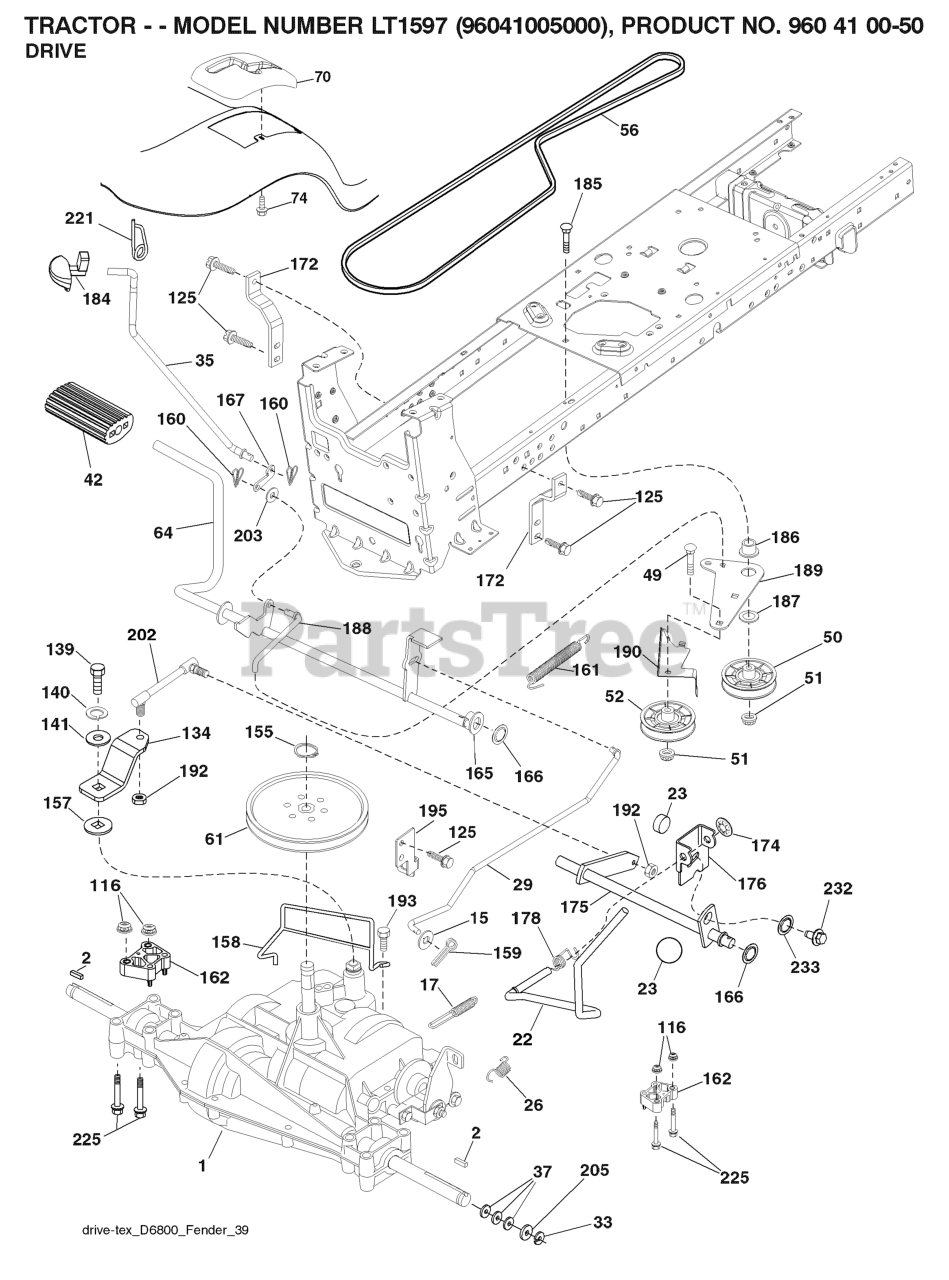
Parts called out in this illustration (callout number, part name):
2	SQUARE KEY
15	WASHER
17	SPRING.BRAKE.PEERLESS.TEX
22	ROD.SHIFT.FENDER.TLT.2006
23	KNOB.DUCKHEAD.1/2
26	SPRING.BRAKE.RTN.GR.DR
29	ROD.BRAKE.PEERLESS
35	ROD.CNTRL.PARK.PREDATOR.LT.TEX
42	PEDAL COVER T
50	IDLER.FLAT.910.OFFSET
51	NUT LOCK FLG 3/8-16 UNC
52	IDLER.V-GROOVE.910.OFFSET
61	PULLEY TRANS
64	SHAFT.ASM.PEDAL.BRAKE.
70	CONSOLE.SHIFT.STL.6SP.GREY
74	SCREW.HI-LO.CONSOLE
116	NUT LOCK HEX FLANGE 5/16-18
125	SCREW
134	ARM.SHIFT.
139	BOLT 1/4-28X3/4
140	LOCKWASHER
155	RETAINING RING LT
157	WASH-SHFT PLT LT
158	KEEPER.PMS.18/20.D4365
159	COTTER PIN
160	RETAINER CLIP
161	SPRING.RETURN.CLUTCH.2006
162	SPACER.TRANSAXLE.18&22
165	BUSHING.SHAFT.BRAKE.HAND
166	NUT.PUSH.625.2006
167	LATCH.BRAKE.SPRING
172	STRAP.TRQ.LH.GEAR.DRIV
174	NUT.PUSH.500.2006
175	SHAFT.ASM.SHIFT.
176	ARM.CLEVIS.ROD.SHIFT
178	SPRING.SHIFT.GT2006
184	HANDLE PARKING BRAKE
186	SPACER.RETAINER
187	WASHER 12/32X2X10GA
188	RP.LINK.CLUTCH.GROUND.DRIVE
189	BELLCRANK.GROUND.DRIVE.TEX.
190	KEEPER.BELLCRANK.DRIVE
192	NUT LOCK CENTER 1/4 -28 FNTHD
193	SCREW 5/16"
195	BRKT.ROD.BRAKE.PEERLES
202	LINK.TRANSAXLE.D6800.18/20"TEX
203	WASHER
221	RETAINER.SPRING.CLIP.H
225	BOLT.HEX.FLNG.5/16-18X3.75
232	BOLT FIN HEX 7/16-14 X 1
233	WASHER SERRATED
